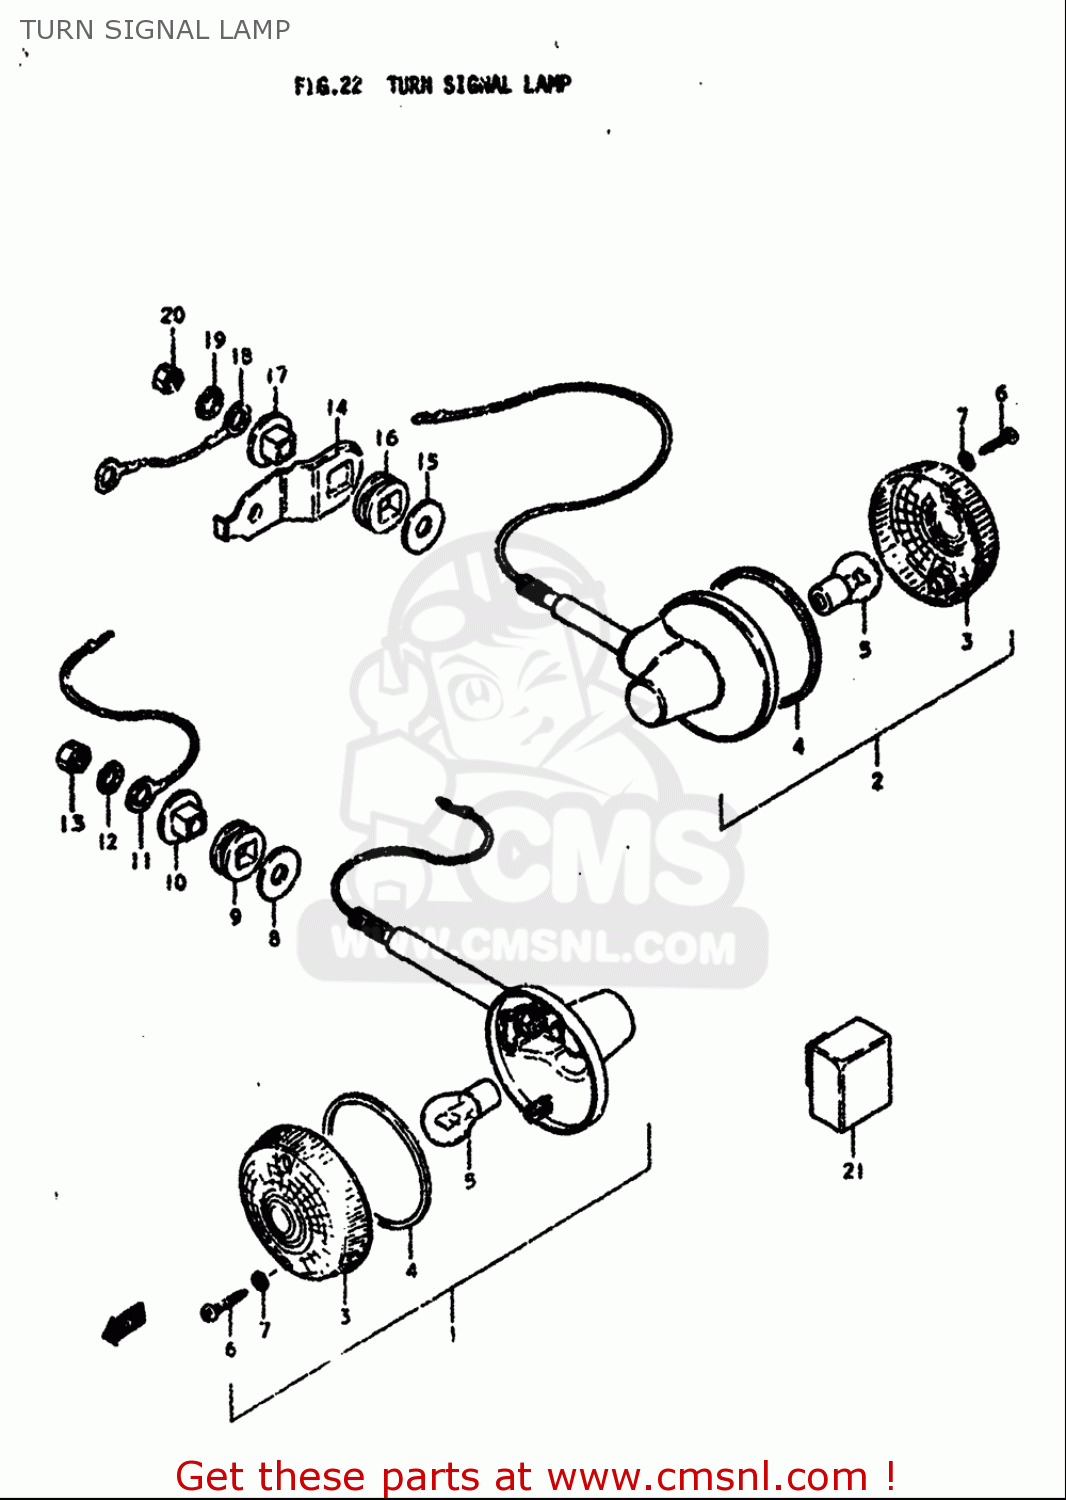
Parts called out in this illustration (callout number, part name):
1	LAMP ASSY,FR TURN SIGNAL
2	LAMP ASSY,TURNSIGNAL
3	LENS
4	GASKET (NAS)
5	BULB(6V17W,STANLEY,A4513A)
6	SCREW
7	GASKET (NAS)
8	WASHER(10.5X30X2.3)
9	CUSHION
10	SPACER
11	LEAD WIRE,EARTH
12	WASHER,LOCK
13	NUT
14	BRACKET,REAR TURN SIGNAL
15	WASHER(10.5X30X2.3)
16	CUSHION
17	SPACER
18	LEAD WIRE,EARTH
19	WASHER,LOCK
20	NUT
21	RELAY ASSY,TURNSIGNAL
